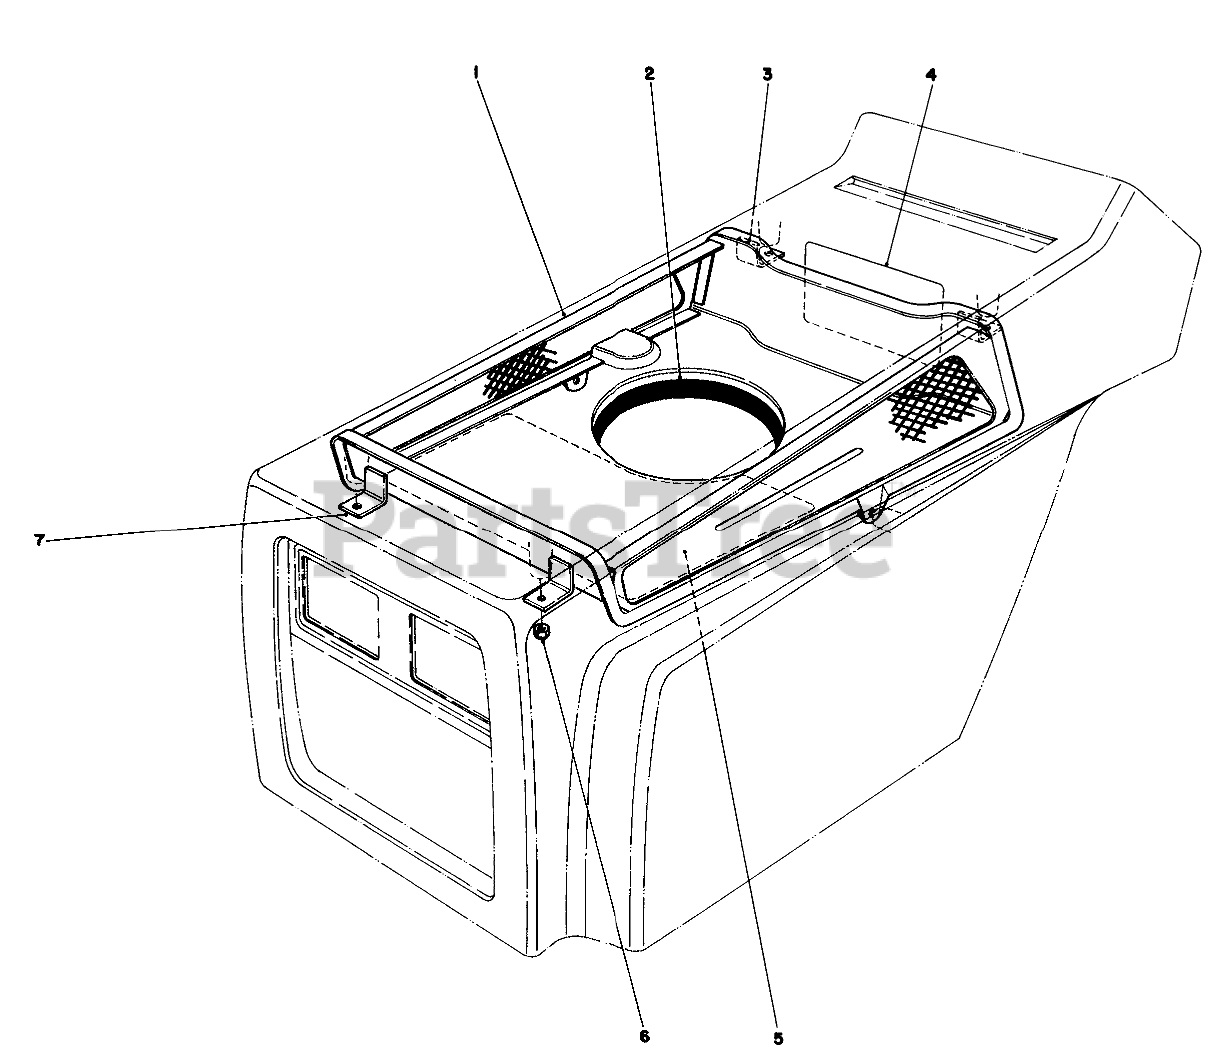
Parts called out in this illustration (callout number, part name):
1	Duct Hood
2	Seal Engine
3	Bracket Rear Duct Support
4	BELT DECAL
5	Decal Service
6	NUT-LOCK, NI
7	Bracket Duct Support
